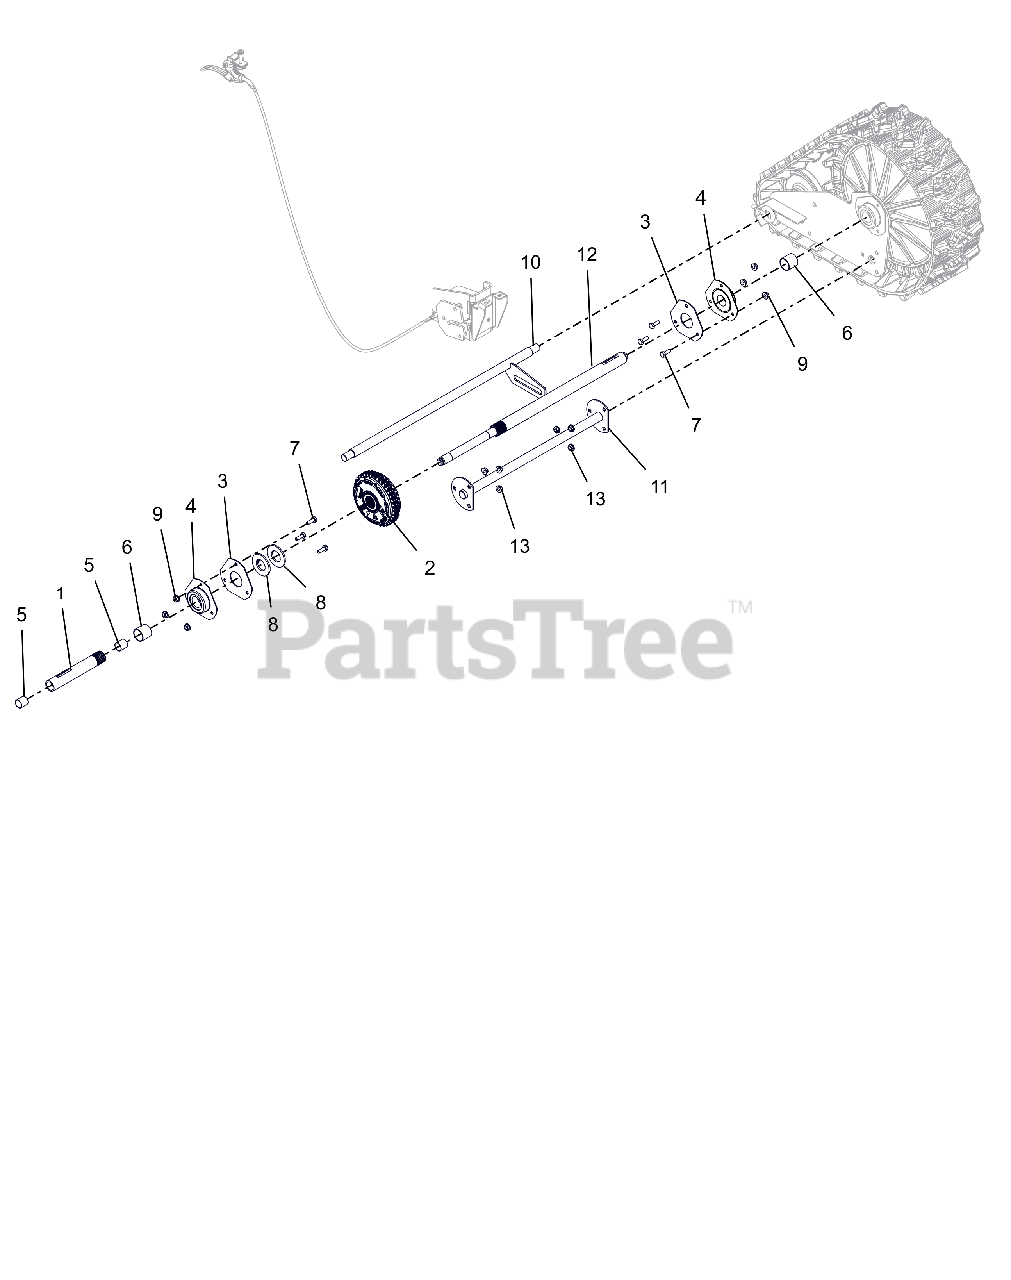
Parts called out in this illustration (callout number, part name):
1	AXLE, SHORT-W/BUSHINGS
2	DIFFERENTIAL, AUTOMATIC
3	PLATE, BEARING SPACER
4	BRG-FLG 1.003/1.000 3 BOLT
5	BSHG-SLV .706X.764X.75 BRZ
6	BSHG-SLV, 1.012X1.125X1.00
7	BLT, HEX .25-20X.75 G5 ZCC
8	WSHR, FLT 1.062X2.000X.134 ZCC
9	NUT-LK-CTR-FLG .25-20 ZC120
10	AXLE, REAR-BWT WLDMT
11	SUPPORT, FRONT-BWT
12	AXLE, LONG-TRACK DIFFERENTIAL
13	NUT-LK-TOP-FLG .250-20 GF ZCC
